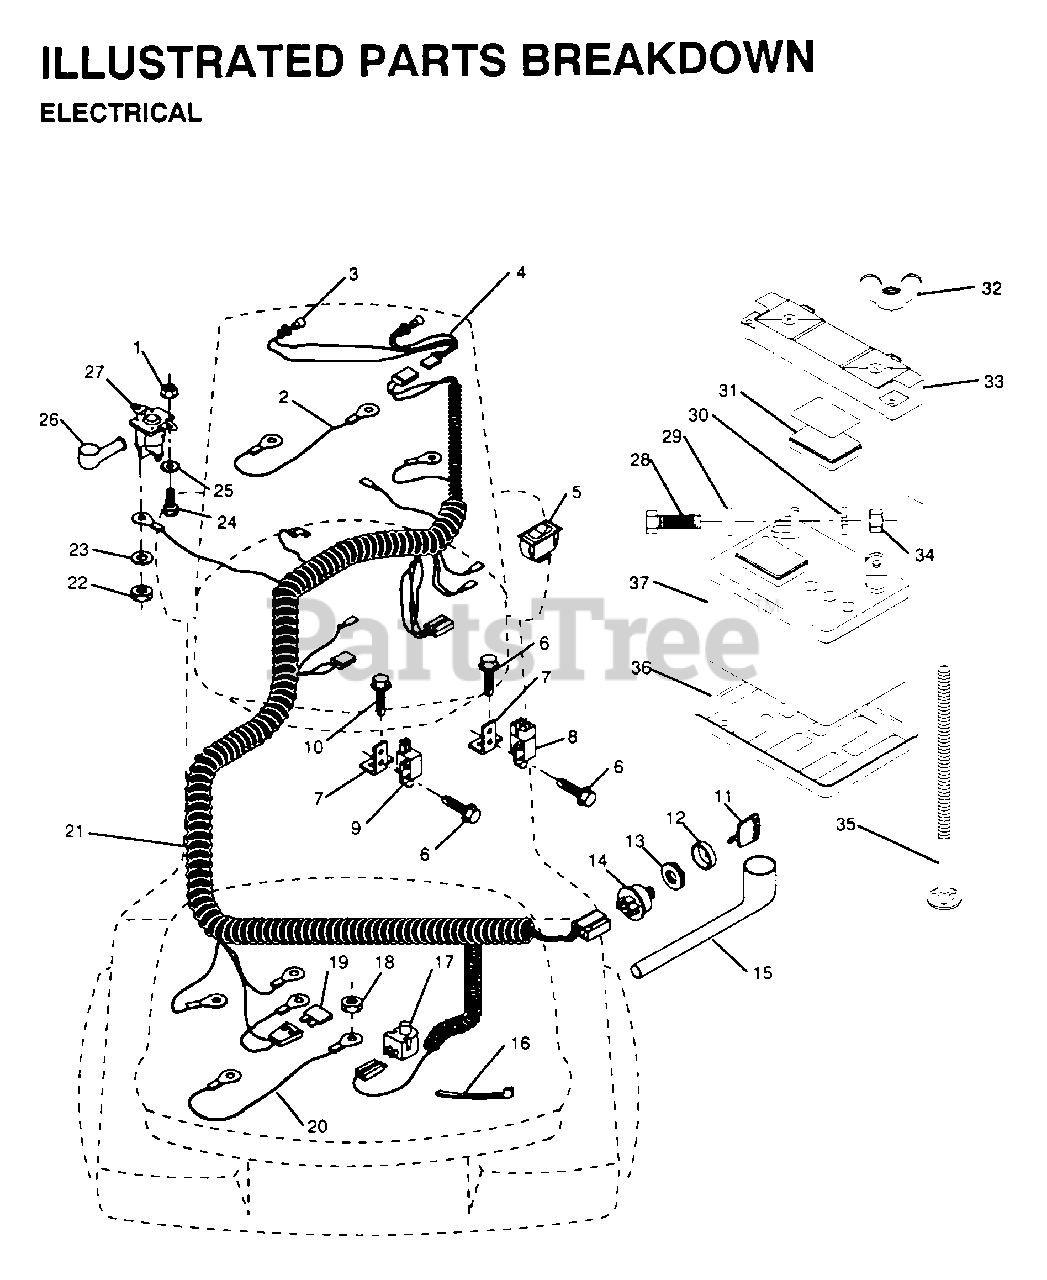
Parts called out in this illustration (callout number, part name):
1	NUT
2	CABLE LTV
5	SWITCH LT
6	SCREW
7	BRACKET LT
8	SWITCH INTERLOCKT
9	SWITCH-INTER. GT
10	SCREW
11	KEY
13	NUT IGNITION
15	COVER IGNITION SW
16	WIRE TIE
17	SWITCH SEAT
19	FUSE HYT
21	HARNESS IGNITION
22	NUT
24	BOLT
28	BOLT LT
29	WASHER
30	LOCKWASHER
35	BOLT
36	"TRAY T, BATTERY"
